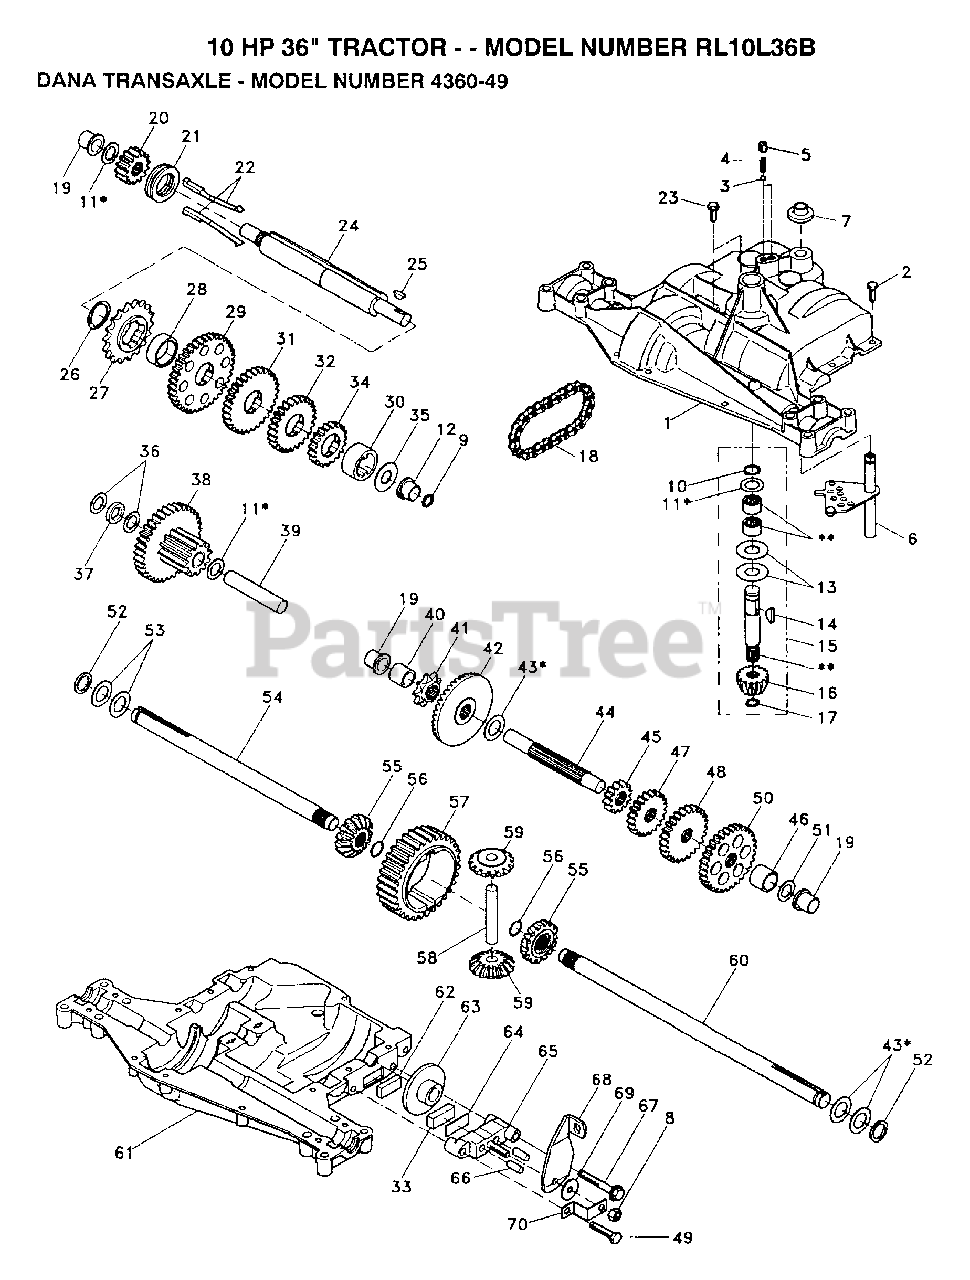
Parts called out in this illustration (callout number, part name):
4	"SPRING, DETENT LT"
5	"SCREW, SET LT"
6	KIT SHIFTER ASM
7	SHIFTER BOOT
8	NUT.LOCK.5/16-24
9	SQUARE RING
10	RETAINING RING LT
11	ASM KIT SHIM 4689
12	"FLANGE, BEARING"
13	WASHER T
14	WOODRUFF KEY
15	AS KIT INPUT SHFT
16	PINION 14T T
17	"RING,RETAINING LT"
18	"CHAIN,24 PTCH LT"
19	BEARING.FLNG.5510
20	GEAR SPUR 14T
21	COLLAR CLUTCH
22	ASM KIT CLTCH KEY
23	SCREW TAP W/SEAL
24	SHAFT INTERM
25	WOODRUFF KEY
26	"RING,RETAINING LT"
27	SPROCKET 18T T
28	SPACER YT
29	KIT.GEAR.12/37TH
30	SPACER
32	GEAR 25T LT
33	PUCK T
34	SPUR GEAR 19T
35	"WASHER, PLAIN LT"
36	WASHER 025
37	SPACER
38	ASSM GEAR COMB
39	SHAFT IDLER
40	SPACER T
41	SPROCKET 9T LT
43	ASM KIT SHIM
44	SHAFT T
48	"GEAR, SPUR 25T LT"
49	"SCREW, TAPPING LT"
50	"GEAR, SPUR 31T LT"
51	WASHER 060
52	NEOPRENE WASHER
53	WASHER 031
55	GEAR 15T T
56	"RING,RETAINING LT"
58	SHAFT T
59	GEAR 1ST T
62	PUCK T
63	BRAKE DISC. T
64	SPACER LT
66	PIN T
69	WASHER LT
